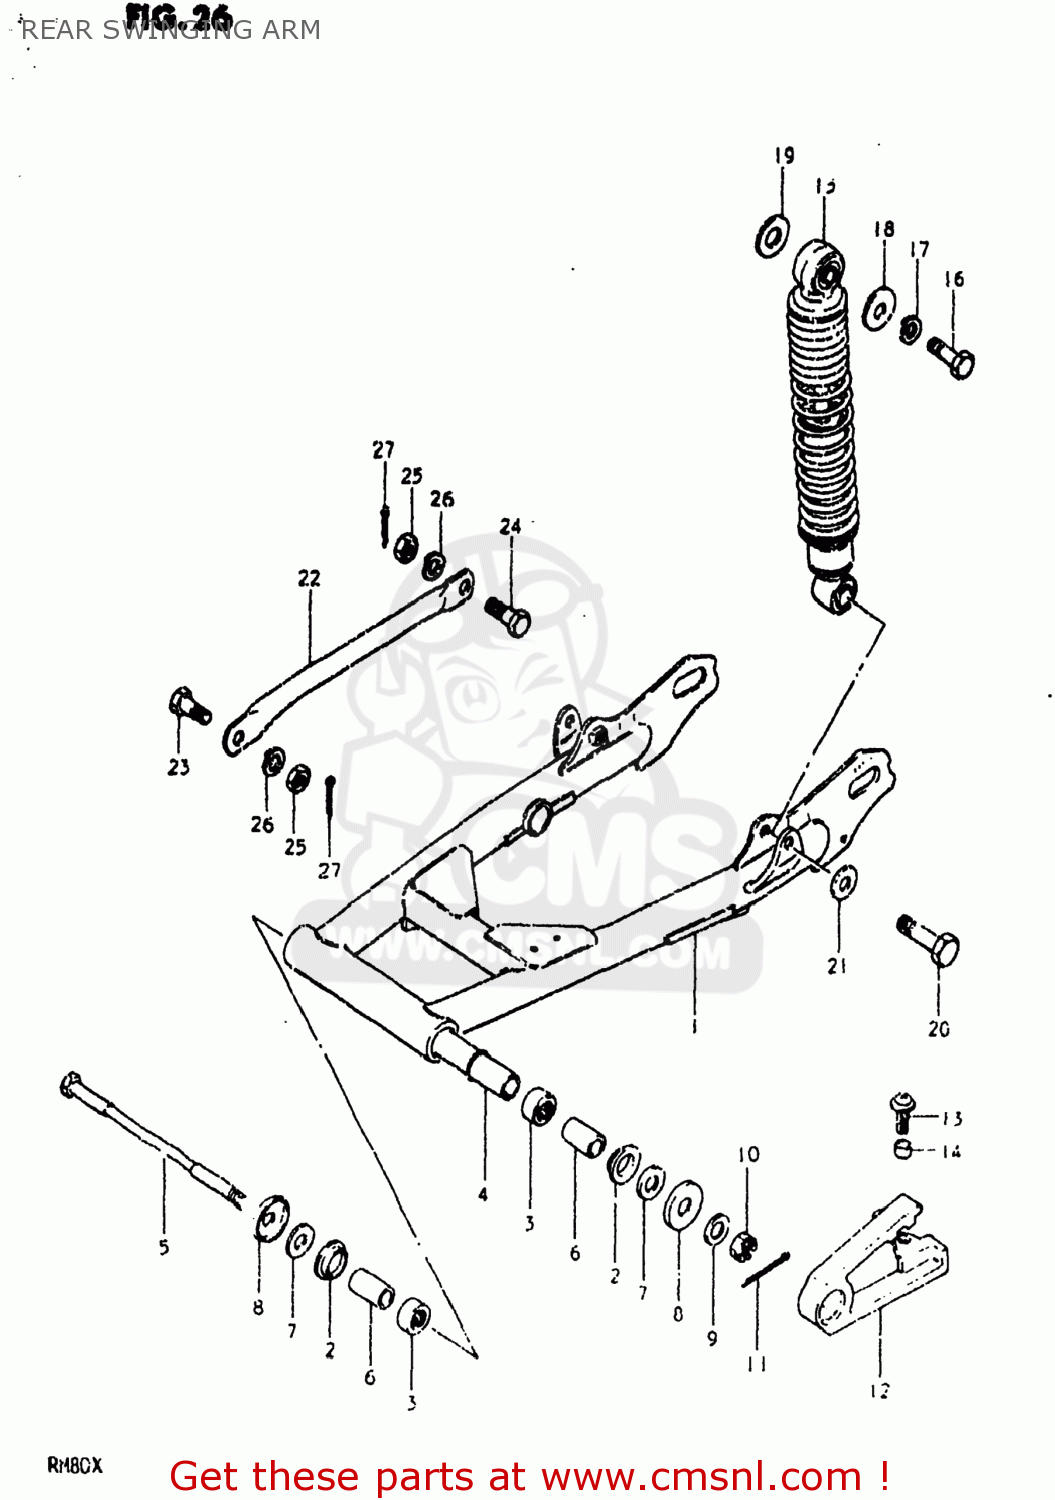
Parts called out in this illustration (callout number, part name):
1	SWING ARM ASSEMBLY,REAR
2	BUSH,RR SWINGINGARM PIVOT
3	ROLLER BEARING (17X24X2
4	SPACER,SWING ARM,CENTER
5	SHAFT,REAR SWING ARM
6	SPACER,RR SWGARM PIVOT
7	WASHER
8	COVER,REAR SWING ARM DUST
9	WASHER
10	NUT, REAR AXLE
11	COTTER PIN
12	BUFFER,CHAIN TOUCH DEFLECTOR
13	SCREW,CHAIN TOUCH DEFEND
14	SPACER (5.5X8X4)
15	ABSORBER ASSEMBLY,REAR SHOCK
16	BOLT
17	LOCK WASHER
18	WASHER (6.5X24X1.6)
19	WASHER
20	BOLT
21	WASHER
22	TORQUE LINK,REAR
23	BOLT(8X22)
24	BOLT(8X26.5)
25	NUT
26	LOCK WASHER
27	PIN
